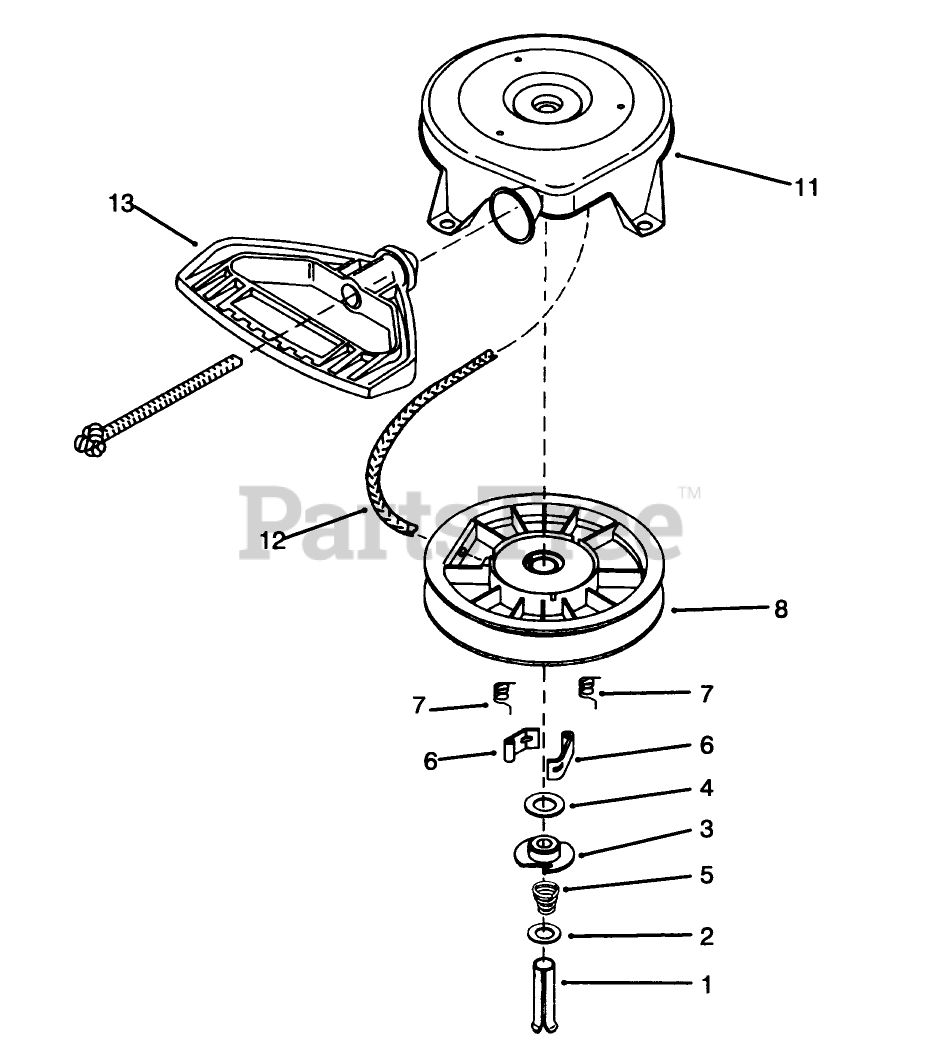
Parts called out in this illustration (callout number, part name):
1	Pin, Spring (Incl. Ref. #7)
2	Washer
3	Retainer
4	Washer
5	Spring-Brake
6	Dog-Starter
7	Spring-Dog
8	Pulley and Rewind Spring ASM
11	Housing Assy.-Starter
12	Rope-Starter
13	Handle-Starter, Mitten Grip
